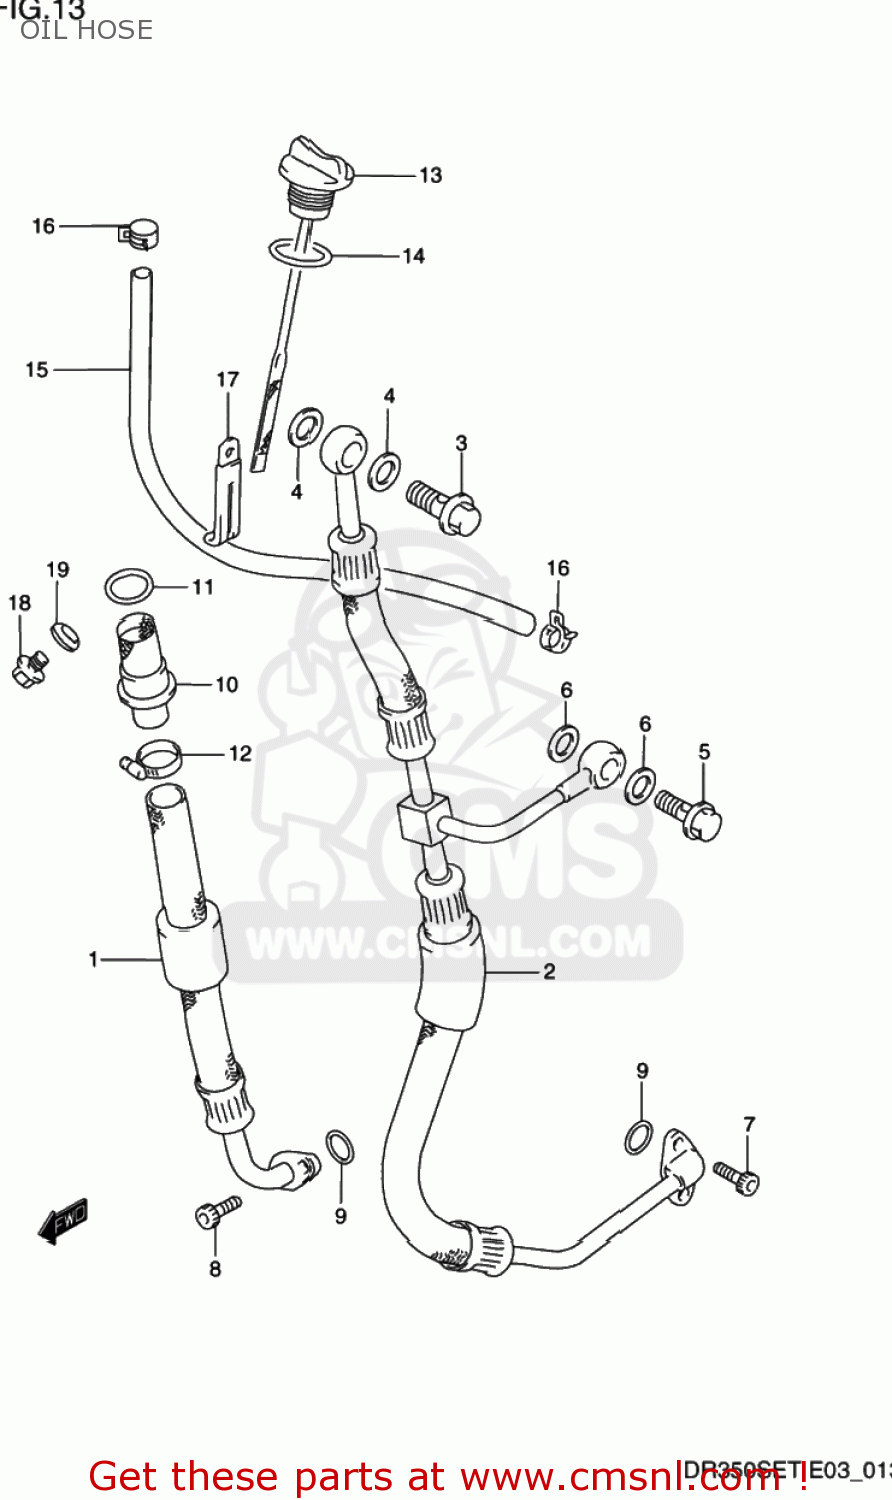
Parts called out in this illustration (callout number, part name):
1	HOSE,OIL
2	HOSE,OIL
3	BOLT UNION
4	GASKET(16X22X2) (NAS)
5	BOLT UNION
6	GASKET(12X17X1) (NAS)
7	BOLT
8	BOLT
9	O RING(D:2.4,ID:12.3)
10	STRAINER,FRAME HEAD UNDER
11	O RING(D:3.1,ID:22.7)
12	CLAMP
13	GAUGE ASSY,OIL LEVEL
14	O RING(D:3.1,ID:16.8)
15	HOSE,OIL OVER FLOW
16	CLIP
17	CLAMP(L:55)
18	PLUG
19	GASKET(10X14X3.6) (NAS)
